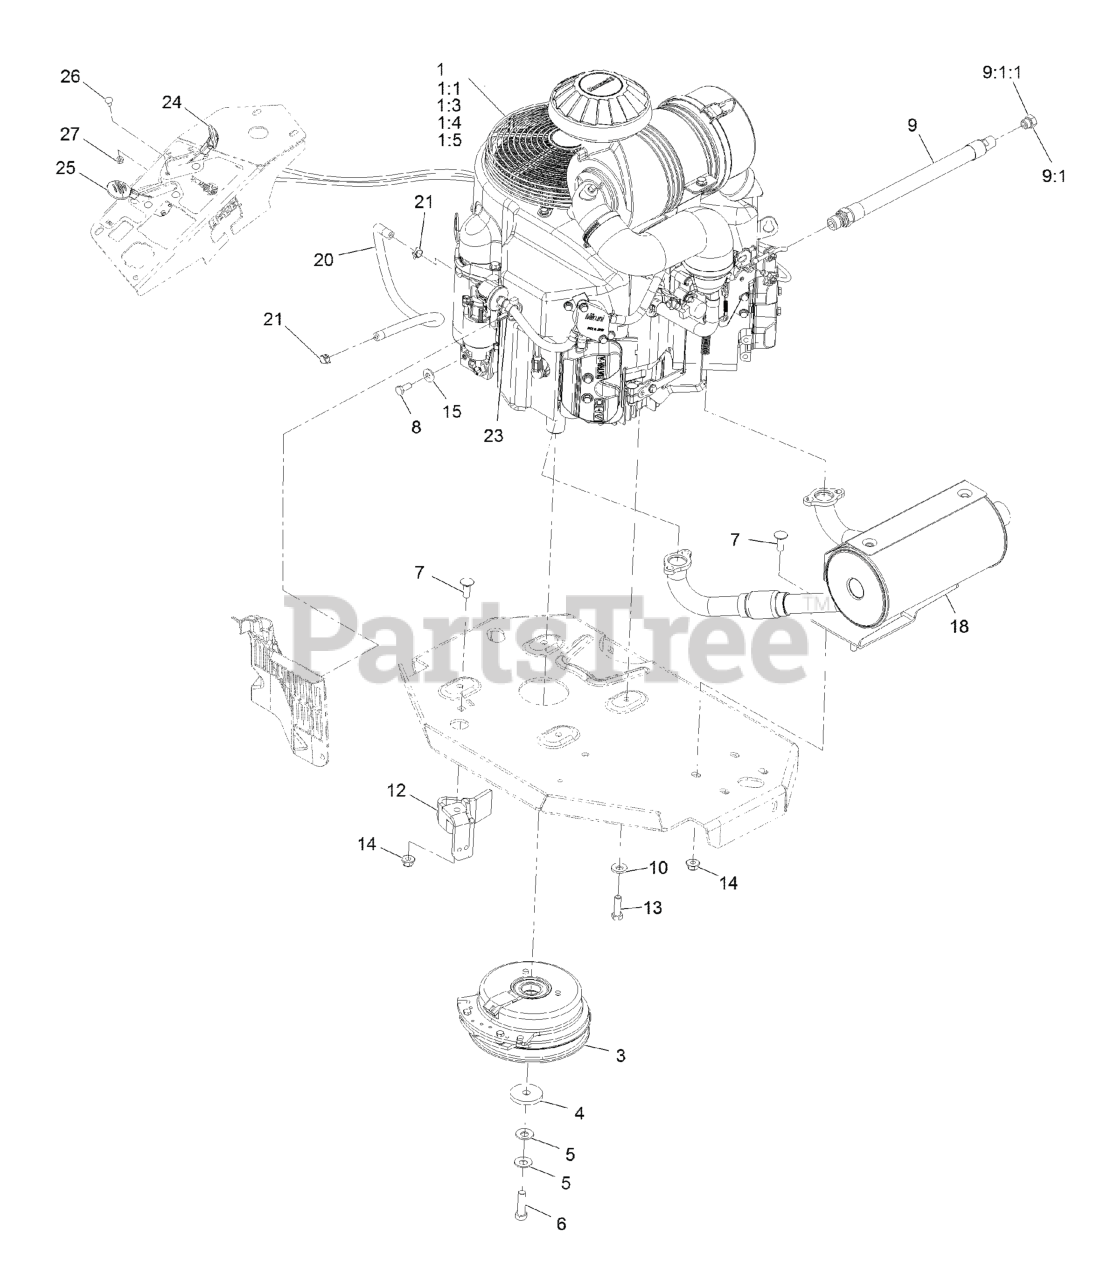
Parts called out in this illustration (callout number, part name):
1:1	Kawasaki 49065-2078 Engine Oil Filter
1:3	Kawasaki 49019-0031 Fuel Filter
1:4	Kawasaki 11013-7039 Safety Filter
1:5	Kawasaki 11013-7038 Air Filter
3	CLUTCH KIT
4	WASHER-CLUTCH
5	WASHER-SPRING
6	SCREW-HH 7/16-20 X 1 1/2 W/LOCTITE
7	SCREW-CARR
8	SCREW-HH
9	ENGINE OIL DRAIN HOSE ASM
9:1	PLUG-HH
9:1:1	O-RING
10	WASHER-BELLEVILLE
12	CLUTCH-ANCHOR
13	SCREW-HH
14	NUT-HF, NI
15	WASHER-SPRING
18	MUFFLER, FX850/801 FLEX
20	HOSE-FUEL
21	CLAMP-HOSE
23	CLAMP-HOSE
24	ASM, CHOKE CABLE
25	ASM,THROTTLE CABLE
26	BOLT-CARR
27	NUT-LOCK, NI
